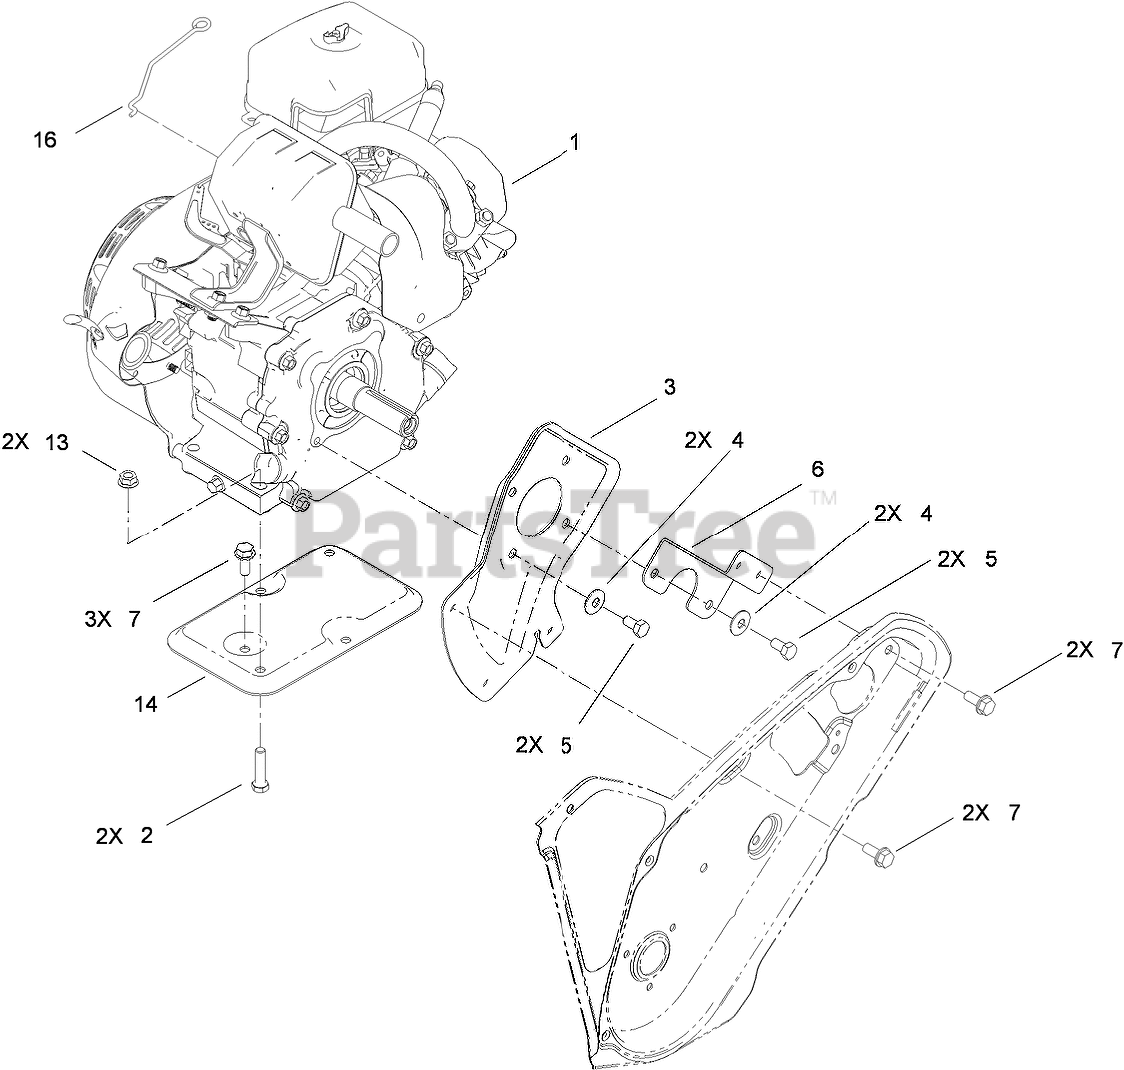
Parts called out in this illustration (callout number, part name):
1	ENGINE-LC168FS-1
2	SCREW-HH
3	PLATE-ENGINE, PTO
4	WASHER-BELLEVILLE
5	SCREW-HHF
6	SUPPORT-ENGINE, SIDE
7	SCREW-HWHTF
13	NUT-HF
14	SUPPORT-ENGINE
16	LINK-KNOB, CHOKE
